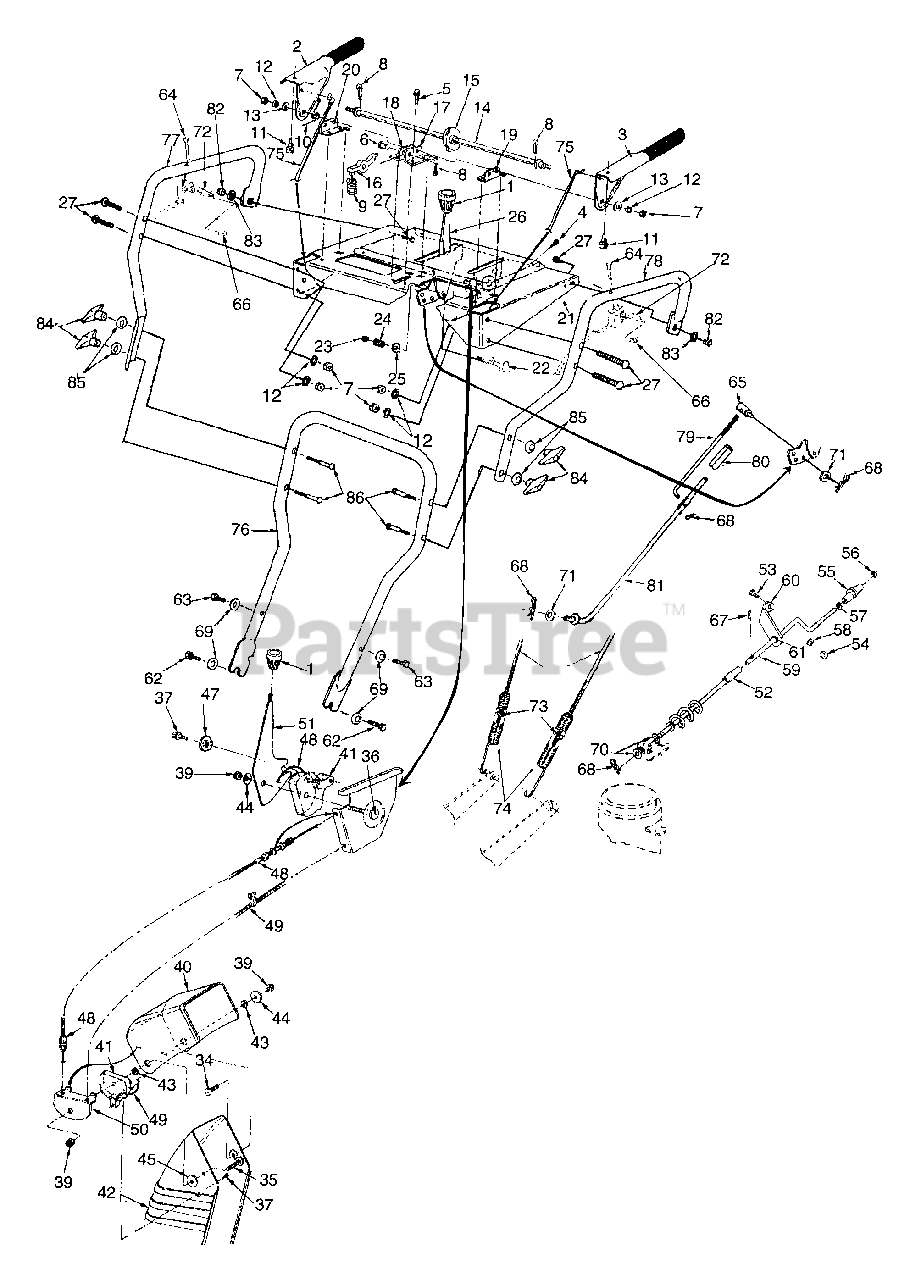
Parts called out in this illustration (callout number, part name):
1	Sml Shift Knob 1.6 Dia Sentar
2	Engage Handle Le Blk Dip Rh
3	Engage Handle Lf Blk Dip Lh
4	Pan Head B-tapp Scr #10 X .5
5	Hhhd Sf-tap Scr 1/4-20 X 1/2 Zn
6	Clevis Pin .31 Dia X 1.0
7	Nut Hex 5/16-18 Gd 5
8	Cot-pin 3/32 Dia X 1.0
9	Comp Spring .36 Dia X 1.0 Lg
10	Spring Torsion .44 Id
11	Rubber Bumper .63 Dia
12	Lock Washer 5/16
13	Wsher Spcl. .345 Sq. X .72 Od
14	Cam Rod
15	Clutch Lock Cam
16	Clutch Lock Pawl
22	Scr Hex Cap 3/8-24 X 1.5 Gd 5
23	Hex Ins L-nut 3/8-24
24	Compression Spring .39 Id X .88
25	Bell Wash .40 Id X .88 Od X .06
34	Carriage Bolt 5/16-18 X 1.00
35	Carriage Bolt 5/16-18 X 1.75
36	Hex Scr 5/16-18 X 1.5
37	HWHD 6 Tapp Scr 1/4 X 5/8 Zn
39	Hex Ins L-nut 5/16-18
40	6" Upper Chute Remote Tilt
41	Chute Tilt Cable Guide
42	6" Lower Chute Remote Tilt
43	Chute Pivot Spacer
44	Fl-wash .344 Id X .88 Od X .063
45	Fit Wshr .344 X 1.125 X .125
47	Contoured Washer
48	Chute Control Cable 66"
49	Chute Control Cable 66" W/clip
54	Hex Nut 1/4-20
55	Chute Crank Knob Countersink
56	Push Cap 3/8 Palnut #375011
57	Flat Washer .38 Id X .60 Od X .033
58	Bell Wash .26 Id X .75 Od X .06t
61	Plastic Bushing .380 Id
62	Hex Scr 3/8-16 X .75
63	Hex Scr 3/8-16 X 1.75
64	Scr Oval C/sunk #10-24 X 1.75
65	Adjustment Ferrule
66	#10-24 Flat Weld Nut
67	Internal Cot-pin 1/2 Dia
68	Inter Cot-pin 5/16 Dia
69	Bell Wash .4 Id X .88 Od X .06
70	Fl-wash .406 Id X .74 Od X .063
71	Fl-wsh Sae .34 X .68 X .062
72	Trgr Asm Steer
73	Hex Ins L-nut 1/4-20
74	Extension Spring
75	Cbl Clutch Drv
79	Upper Shift Rod 5/16 X 10.57
80	2 Pc Shift Rod Connector
81	Rod Shift Lwr 3/8 X 14.75
82	Hex Nut 1/4 - 20
83	Bell Wash .26 Id X .75 Od X .06t
84	Wingnut
85	Bell Wash .345 Id X .88 Od X .060
86	Carriage Bolt 5/16 - 18 X 2.5
